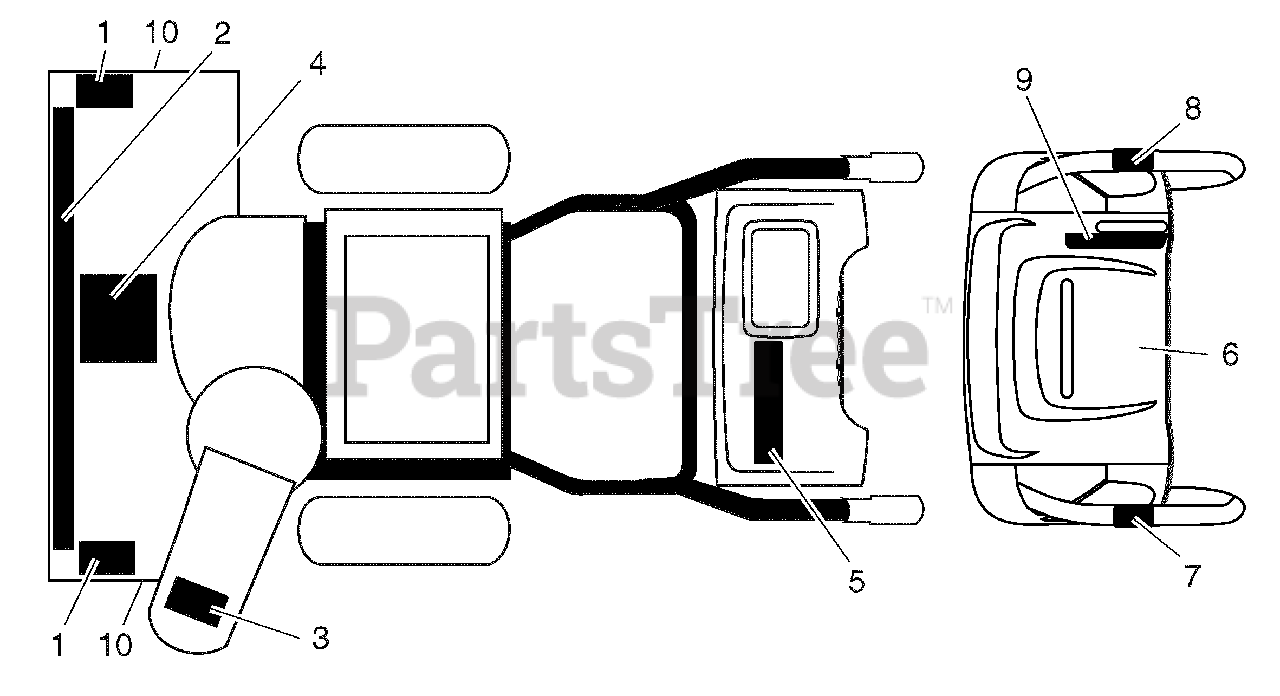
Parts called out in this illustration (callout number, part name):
1	Decal, Danger
2	Decal, Husqvarna
3	Decal, Danger, Deflector
4	Decal, Danger
5	Decal, Husqvarna, 5524STE
6	Decal, Instruction
7	Decal, Traction Lever
8	Decal, Auger Lever
9	Decal, Speed Control
10	Decal, Husqvarna, Crown
10	Owner’s Manual, English
10	Owner’s Manual, French
